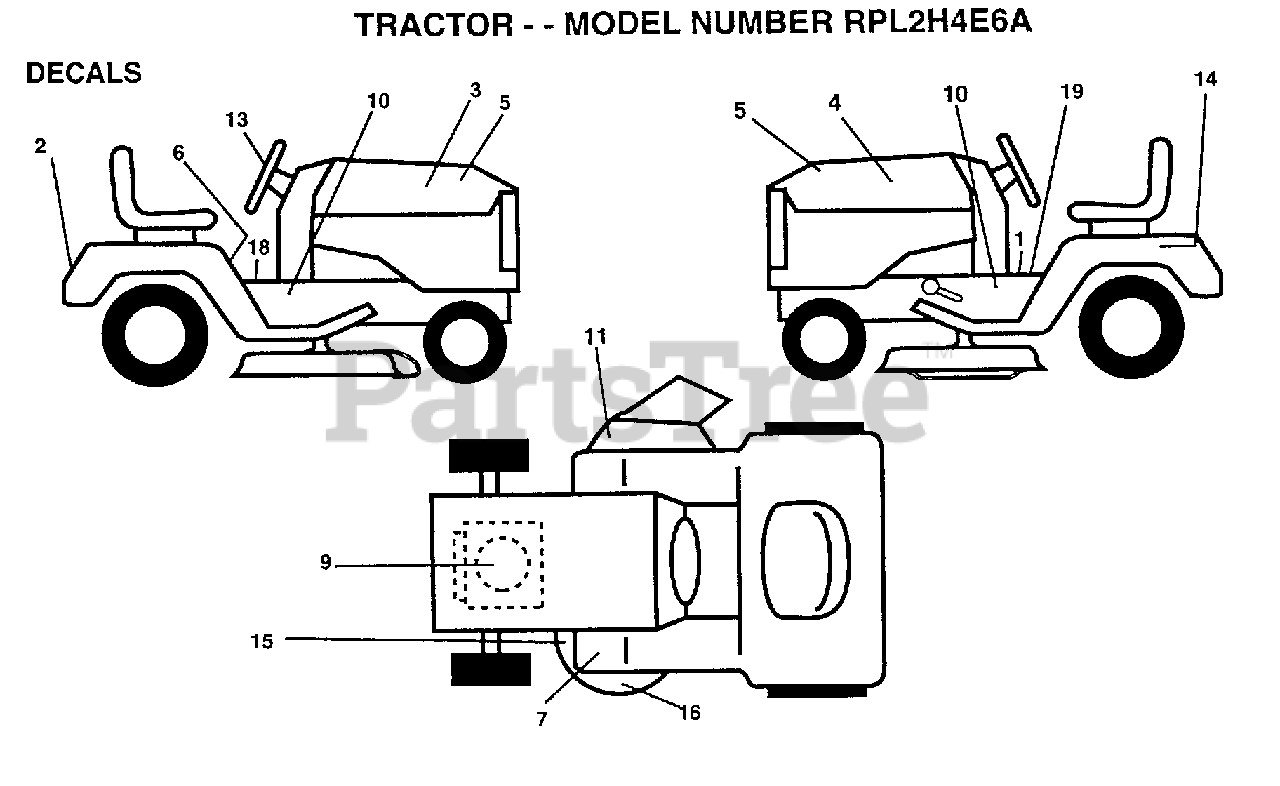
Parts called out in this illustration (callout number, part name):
1	DECAL DASH INS OP
2	FENDER DECAL
3	DECAL HOOD RH
4	DECAL HOOD LH
6	DECAL CAUTION
7	DECAL T
9	DECAL, HP ENGINE
10	DECAL CHAS 42 HYD
11	"DECAL, WARNING"
13	"DECAL,STR WHL"
14	DECAL.BTRY.DANGER
15	DECAL
18	DECAL SADL HYDRO
19	DECAL BRAK PARK
